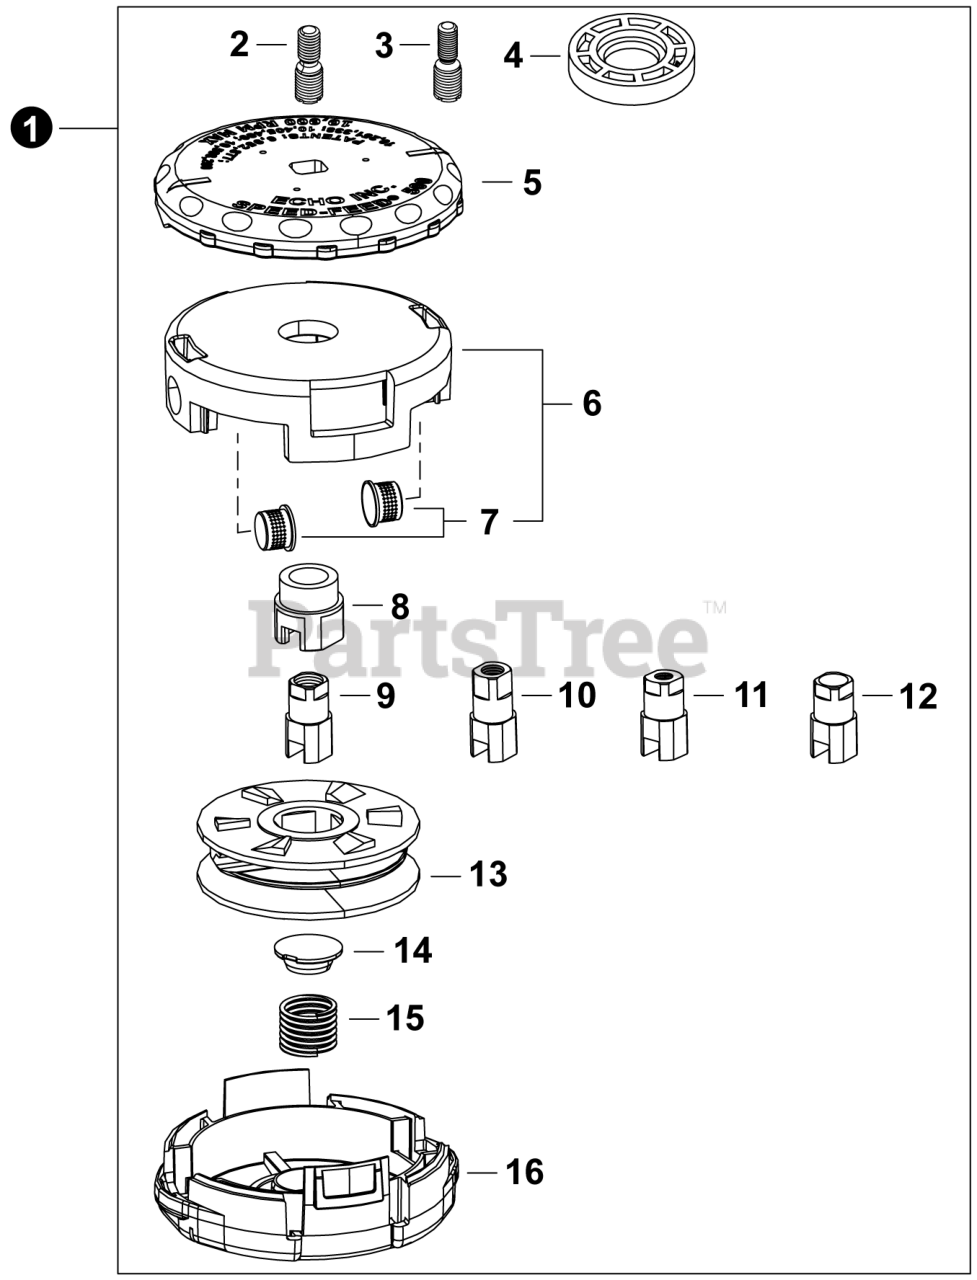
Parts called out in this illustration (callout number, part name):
1	TRIMMER HEAD, SPEED-FEED® 500
2	BOLT, STUD M7x1.00 /M10x1.25 LH GOLD
3	BOLT, STUD M8/M10x1.25 LH SILVER
4	SPACER, BLACK
6	HOUSING ASSY, SPOOL
8	HUB, SPOOL
9	BUSHING 10MMx1.25 LH GOLD
10	BUSHING 10MMx1.00 LH
11	BUSHING 8MMx1.25 LH RED
12	BUSHING 10MMx1.00 LH GREEN
13	SPOOL LH
14	CAP, SPRING
15	SPRING, GOLD
16	COVER, SPOOL
